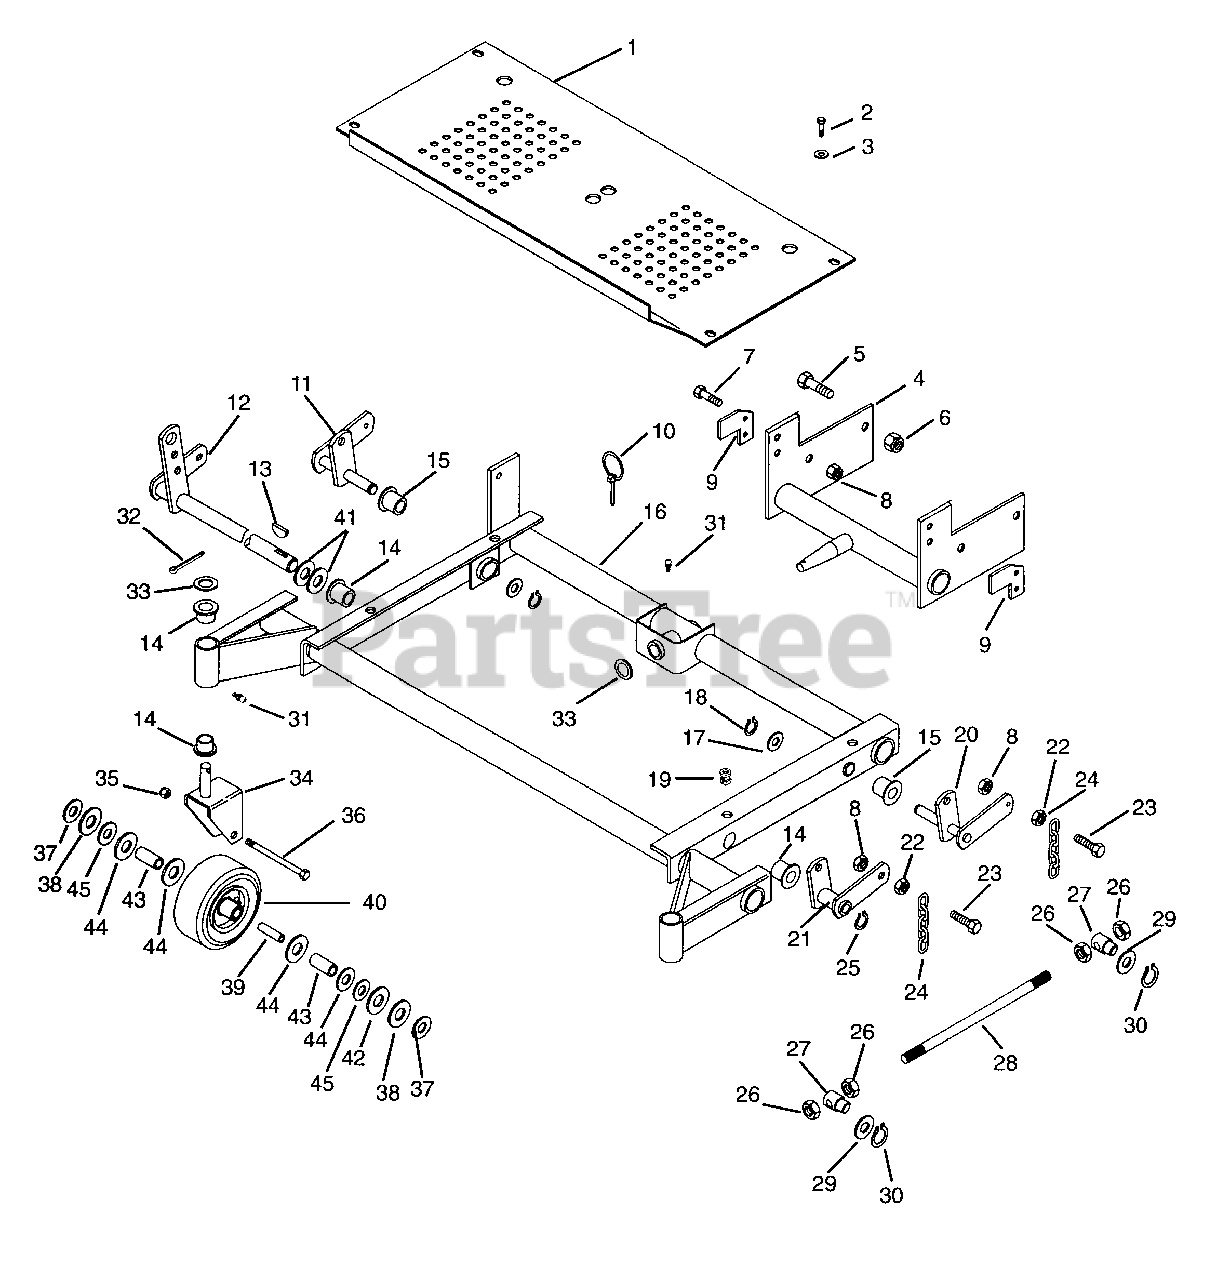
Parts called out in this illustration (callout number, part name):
1	Footboard PM200
2	Screw-Machine-Hex-Washer-Head .25-20 x .75
3	Washer-Flat-Steel .281 x .620 x .065
4	Weldment-Mower Frame Mounting
5	Bolt-Hex .62-11 x 1.50
6	Nut-Locking-Center .62-11
7	Bolt-Hex .38-16 x 1.25 Grade 5
8	Nut-Locking-Center .38-16
9	Plate-Pivot Stop
10	Pin-Klik .25 x 1.75
11	Weldment-Lift Arm Shaft
12	Weldment-Mower Lift Shaft (Front)
13	Key-Woodruff .25 x 1.0
14	Bushing-Flange 1.020 x 1.385 x .75 x 1.75
15	Bushing-Flange .762 x 1.0 x .580 x 1.48
16	Weldment-Front Frame PM200
17	Bearing-N-Thrust .752 x 1.24 x .031
18	Ring-Retaining-External .689 x .077
19	Clip U-Type
20	Weldment-Lift Arm Shaft (R.H.)
21	Weldment-Lift Arm (Front)
22	Nut-Hex .38-16
23	Bolt-Hex .38-16 x 1.50 Grade 5
24	Chain-Link
25	Ring-Retaining-External 1.00 x .078
26	Nut .50-13
27	Pivot-Mower Lift
28	Tie Rod-Lift Lever
29	Washer-Flat-Steel .630 x 1.005 x .062
30	Ring-Retaining-External .625 x .050
31	Fitting-Lube .25-28 x .256
32	Pin-Center .12 x 1.25
33	Bearing-R-Thrust 1.022 x 1.552 x .030
34	Weldment-Caster
35	Nut-Locking-Center .50-13
36	Bolt-Hex .50-13 x 8.00
37	Washer-Flat-Steel .531 x 1.250 x .100
38	Washer-Flat-Steel .813 x 1.370 x .100
39	Axle-Caster
40	Tire/Wheel Assembly 13 x 5-6
40	Tire 13 x 5-6 Turf Trac
41	Washer-Flat-Steel .063 x 2.000 x .134
43	Bearing-Roller
44	Stop Washer
45	Felt-Washer
